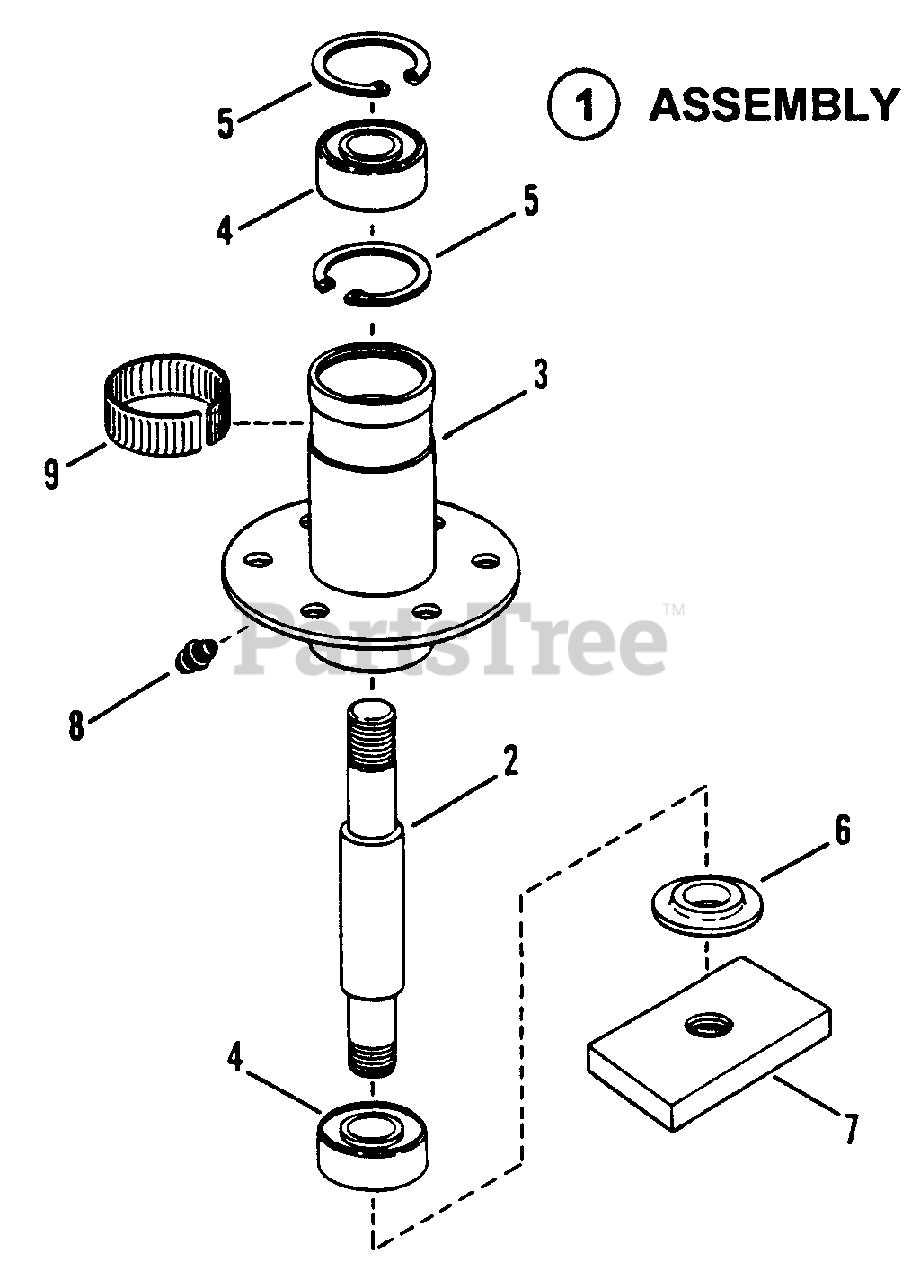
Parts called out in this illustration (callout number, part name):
1	ASSEMBLY, Spindle
2	SPINDLE, (6.06" Long)
2	SPINDLE, (7.25" Long)
3	HOUSING, Spindle (4.25" Tall)
3	HOUSING, Spindle (4.59" Tall)
4	BEARING, Spindle
5	RING, Retaining
6	WASHER, Spindle
7	HOLDER, Blade
8	FITTING, Lube (Press fit for .187 hole-no ball)
9	RING, Tolerance
